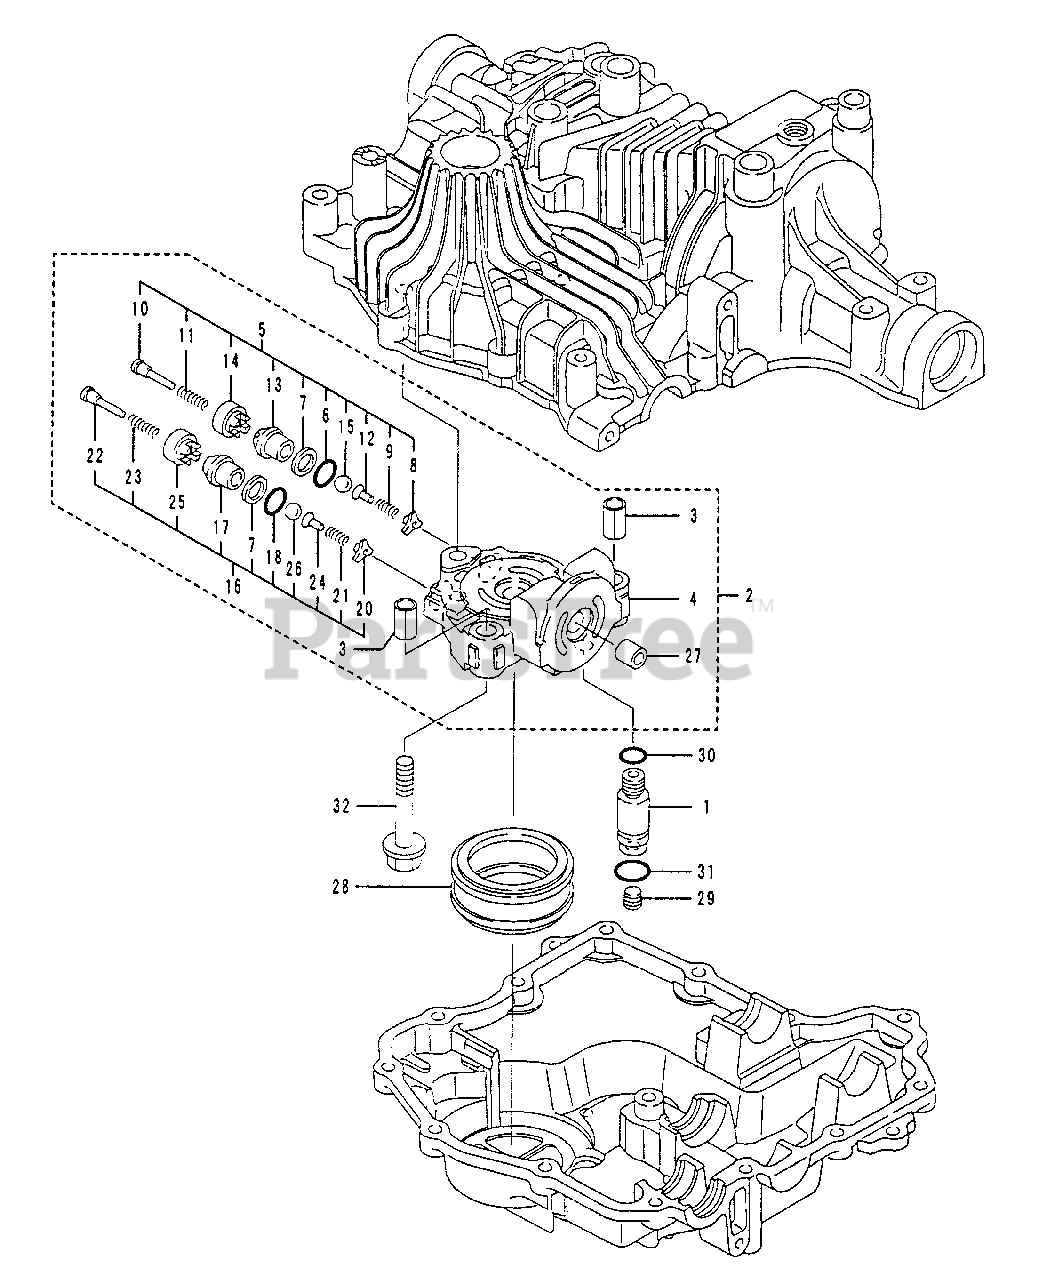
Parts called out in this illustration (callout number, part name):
2	CENTER CASE CMP B
3	KNOCK PIN 12 X 22
4	CENTER CASE
5	VALVE(A-1 SET
6	PACKING 1015
7	BACK-UP RING
8	HOLDER (BYPASS
9	SPRING
10	PUSH PIN
11	SPRING
12	HOLDER (BALL
13	SLEEVE (A-1
14	BODY (B BYPASS
15	BALL 3/8
16	VALVE (A-2 SET
17	SLEEVE (A2
18	PACKING 1015
19	BACK-UP RING
20	HOLDER (BYPASS
21	SPRING
22	PUSH PIN
23	SPRING
24	HOLDER (BALL
25	BODY (B BYPASS
26	BALL 3/8
27	BEARING 12 X 2
30	PACKING P 11
31	PACKING P 14
32	BOLT 10 X 60
